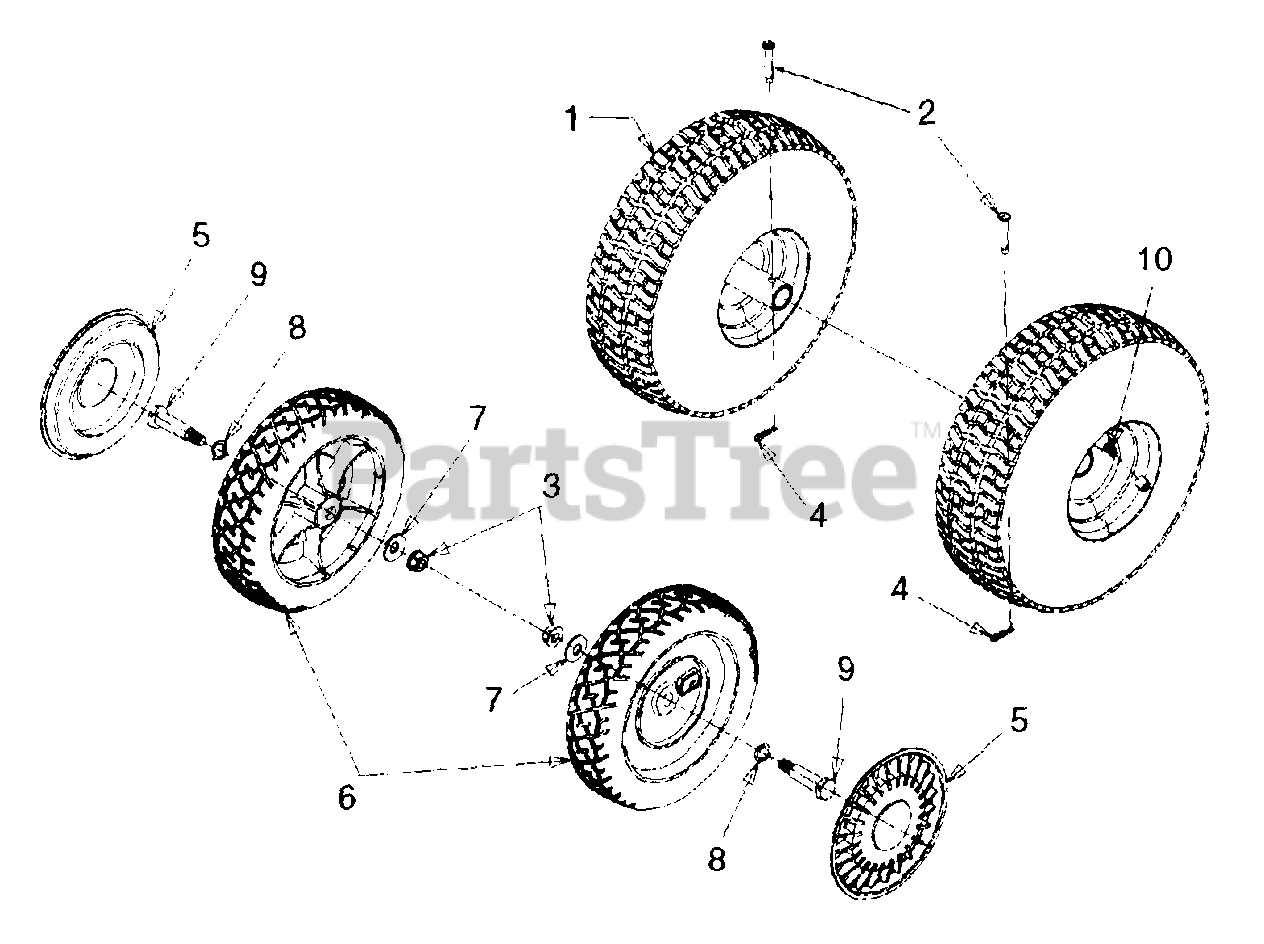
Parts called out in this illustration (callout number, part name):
1	Wheel Ass'y Complete
1	Rim Assembly
1	Tire, Pneumatic, 10 x 4
2	Pin, Clevis, .25 x 1.53
3	Nut, Hex Flange Lock, 3/8-16
4	Pin, Internal Cotter
5	Hubcap, Gray
6	Wheel Ass'y, 8 x 2.0 Complete
7	Washer, Bell, .401 x .870 x .06
8	Washer, Wave, .53 x .78 x .013
9	Shoulder Bolt
10	Valve, Tubeless Air
